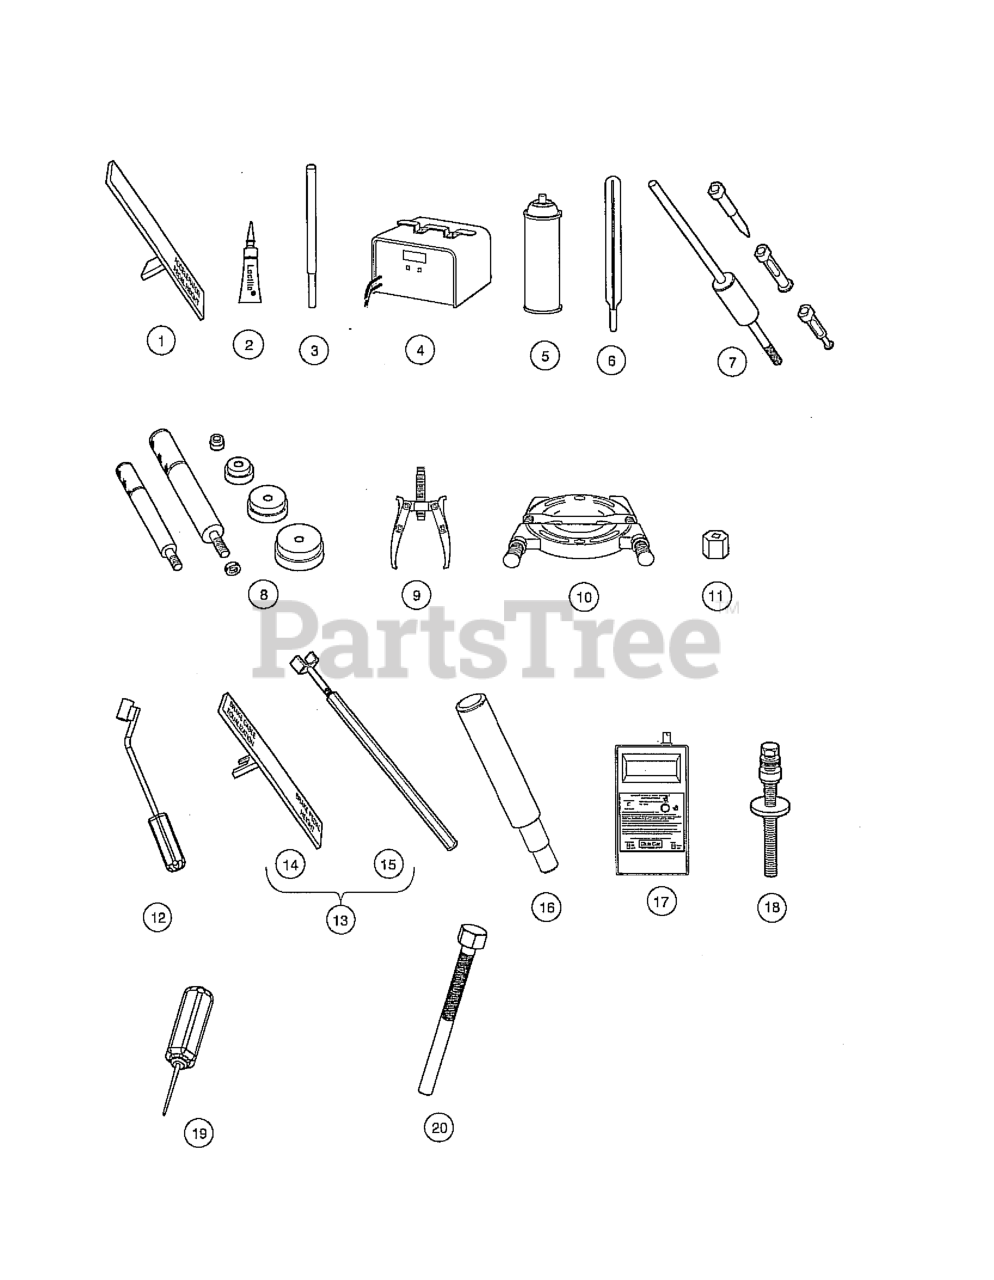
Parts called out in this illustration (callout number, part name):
1	TOOL, ACCEL. PEDAL ADJUSTMENT
2	GUIDE RING ADHESIVE 3 GRAMS
4	BATTERY DISCHARGE UNIT 36/48V
5	BATTERY TERMINAL PROTECT SPRAY
6	BATTERY THERMOMETER
7	BEAR & OIL SEAL REMOVER ASM
8	BEARING DRIVER SET
9	BEARING PULLER
10	BEARING PULLER WEDGE ATTACH.
11	BRAKE ADJUSMENT SOCKET TOOL
12	BRAKE CABLE RELEASE TOOL
17	CALIBRATION & TEST MODULE
18	CAM INSTALLATION TOOL
19	CHARGER BEZEL TOOL
20	TOOL, REMOVAL, CLUTCH, GAS/DSL
